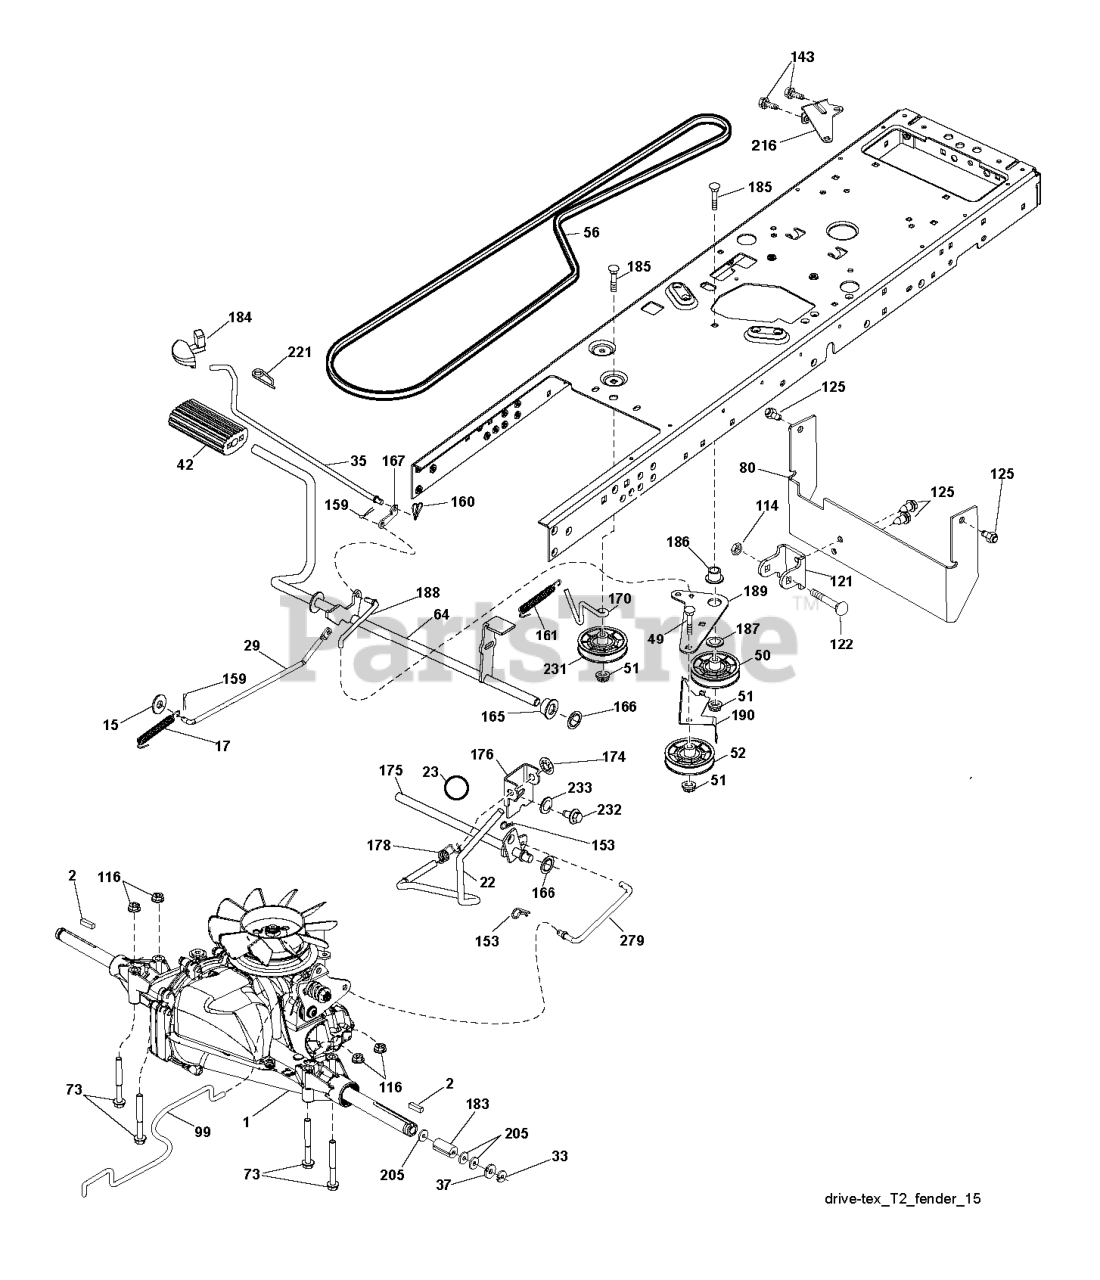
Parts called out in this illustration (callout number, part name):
2	SQUARE KEY
15	WASHER
17	SPRING.BRAKE.HG3000/3500
22	ROD.SHIFT.FENDER.TLT.2006
23	KNOB.DUCKHEAD.1/2
29	ROD.BRAKE.T2.TEX
35	ROD.CNTRL.PARK.PREDATOR.LT.TEX
42	PEDAL COVER T
50	IDLER.FLAT.910.OFFSET
51	NUT LOCK FLG 3/8-16 UNC
52	IDLER.V-GROOVE.910.OFFSET
64	SHAFT.ASM.PEDAL.BRAKE.
73	BOLT HEX 5/16-18 GR 5
80	RP.STRAP.TORQUE.FS.T2
99	ROD.ASM.BYPASS.SPRING.T2.FS
114	NUT.71038.31-18.HEX.NYLOCK
116	NUT LOCK HEX FLANGE 5/16-18
121	BRACKET STRAP TORQUE
122	BOLT.5/16-18X2.5
125	SCREW
143	Screw 5/16-18 x 1/2 Hex, Self Tapping 5/16-18 x 1/2
153	RETAINER M
159	COTTER PIN
160	RETAINER CLIP
161	SPRING, RETURN LT
165	BUSHING.SHAFT.BRAKE.HAND
166	NUT.PUSH.625.2006
167	LATCH.BRAKE.SPRING
170	KEEPER.CENTER SPAN.1.688
174	NUT.PUSH.500.2006
175	SHAFT.ASM.SHFT.T2.TLT
176	ARM.CLEVIS.ROD.SHIFT
178	SPRING.SHIFT.GT2006
183	SPACER, AXLE PVST
184	HANDLE PARKING BRAKE
186	SPACER.RETAINER
187	WASHER 12/32X2X10GA
188	RP.LINK.CLUTCH.GROUND.DRIVE
189	BELLCRANK.GROUND.DRIVE.TEX.
190	KEEPER.BELLCRANK.DRIVE
216	BRACKET.PULLEY.IDLER.W/TEX
221	RETAINER.SPRING.CLIP.H
231	IDLER.V-GROOVE.1.688.OFFSET
232	BOLT FIN HEX 7/16-14 X 1
233	WASHER SERRATED
279	LINK.SHIFT.T2
